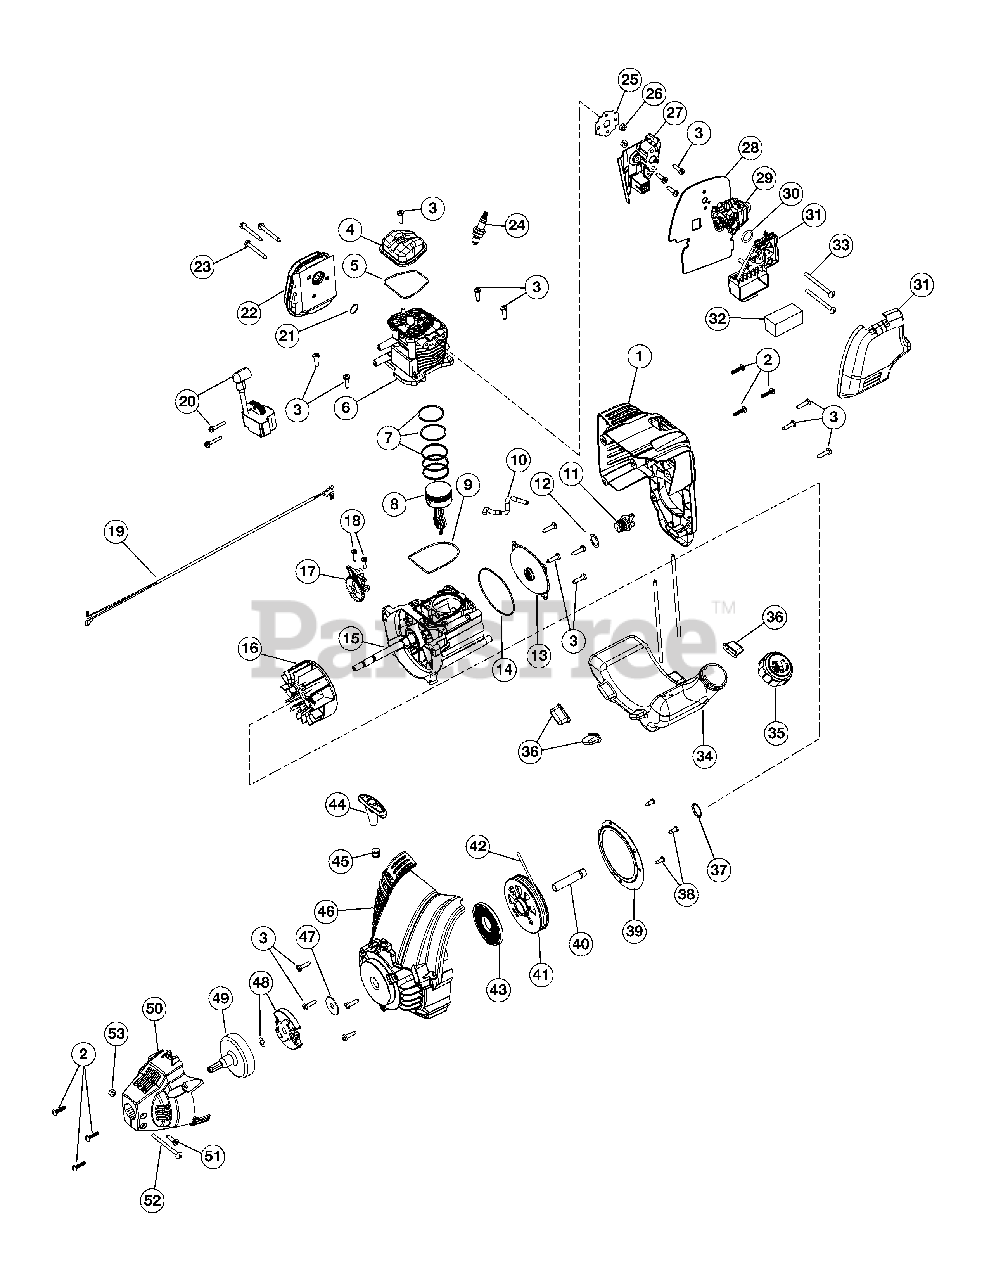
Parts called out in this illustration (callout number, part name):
1	Engine Cover Assembly
2	Cover Screw
3	Screw
4	Rocker Cover
5	Rocker Cover O-Ring
6	Cylinder Assembly
7	Piston Ring Assembly
8	Piston Assembly
9	Cylinder O-Ring
10	Breather Hose
11	Oil Plug
12	Oil Plug O-Ring
13	Crankcase Cover
14	Crankcase Cover O-ring
15	Crankcase Assembly
16	Flywheel Assembly
17	Cam Bracket Assembly
18	Cam Bracket Screw
19	Lead Wires
20	Module Assembly
21	Muffler Gasket
22	Muffler Assembly
23	Muffler Screw
24	Spark Plug
25	Insulator Gasket
26	Nut
28	Carburetor Gasket
29	Carburetor w/Primer
31	Air Cleaner Cover Assembly
32	Air Filter
34	Fuel Tank Assembly w/Fuel Lines
36	Fuel Tank Pads
37	Push Nut
38	Pressure Plate Screw
39	Pressure Plate
41	Starter Assembly
43	Recoil Spring
44	Handle
46	Starter Housing Assembly
48	Clutch & Clutch Washer
49	Clutch Drum
50	Clutch Cover
51	Anti-Rotation Screw
52	Clamp Screw
